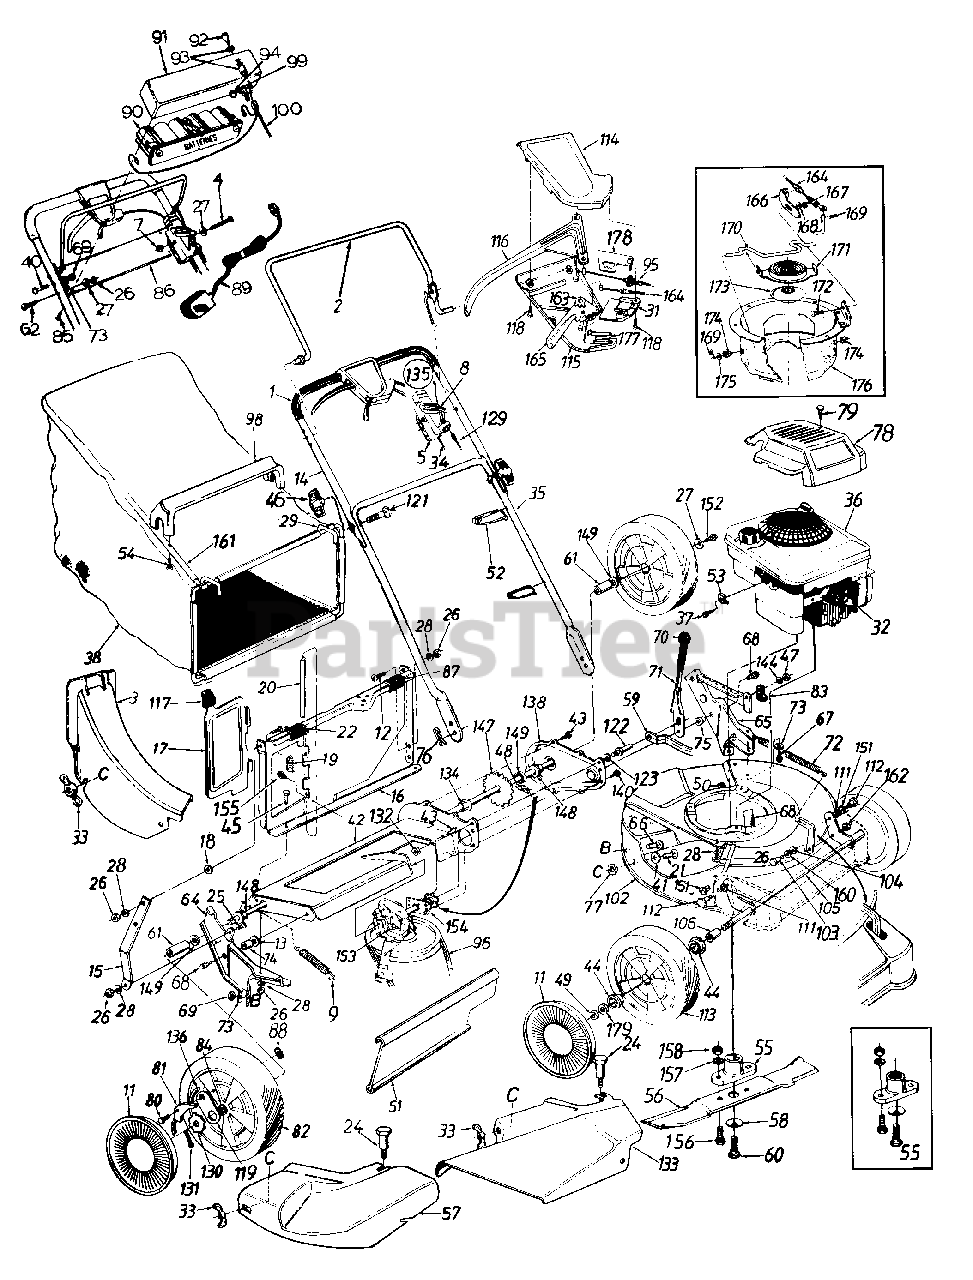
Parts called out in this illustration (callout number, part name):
1	Foam Grip
3	Rear Discharge Chute Ass'y.
4	Hex Bolt 1/4-20 x 2" Lg.
5	Throttle Body
7	Hex L-Nut 1/4-20 Thd.
8	Throttle Lever
9	Ext. Spring 3.8" Lg.
11	Hub Cap
12	Truss Mach. Scr. 1/4-20 x .62" Lg.
13	FL-Wash. .383" I.D. x 1" O.D.
19	Torsion Spring
20	Pivot Pin
21	Carriage Bolt 1/4-20 x .62"
22	Truss Mach. Scr. 1/4-20 x 3/4" Lg.
24	Shoulder Bolt .312 Dia. x . .18 Lg.-Special
25	Hex Bolt 1/4-20 x .62" Lg.
26	Hex Nut 1/4-20 Thd.
27	Bell-Wash. 1/4" I.D.
28	L-Wash. 1/4" I.D.
31	S.P. Control Cover
32	Spark Plug Insulator
33	Wing Nut w/Washer
34	Throttle Control Wire 61"
36	Engine
37	Hex Self-Tap Scr. #10-32 x .62" Lg.
38	Grass Bag
40	Curved Carr. Bolt 5/16-18 x 1.38" Lg.
41	FL-Wash. .344" I.D. x .62"
44	Ball Bearing 1/2" I.D.
45	Hex AB-Tap Scr. 1/4 x .62"
46	Hand Knob
47	Hex Patch L-Nut 3/8-24 Thd.
48	348 Chain .500" Pitch x 30 Links
49	Hex L-Nut 1/2-20 Thd.
51	Rear Flap 4.8" x 18" Lg.
52	Cable Tie
53	Cable Clamp
54	Hex AB Scr. #12 x 1.25" Lg.
55	blade Adapter Kit
56	21" Mulching Blade
57	Mulching Plug
58	Bell-Wash. .46" I.D.
59	Height Adj. Connecting Arm
60	Hex Bolt 7/16-20 x 1.5" Lg. (Grade 5)
61	Spacer .513" I.D. x .703" O.D. x .69" Lg.
62	Carr. Bolt 1/4-20 x 1.25" Lg.
64	R.H. Handle Wheel Brkt. Ass'y.
65	L.H. Handle Wheel Brkt. Ass'y.
66	Carriage Bolt 5/16-18 x .62"
67	Hex Wash. Hd. B-Tap Scr. 5/16-18
68	Hex Wash. Hd. TT-Tap Scr. 3/8-16
69	Hex Nut 5/16-18 Thd.
71	Height Adj. Lever
72	Extension Spring .75" O.D. x 8" Lg.
73	Bell-Wash. 5/16" I.D.
74	Spacer
75	Shld. Spacer .500" Dia.
76	Hairpin Clip
77	Bolt Retainer 1/4 x .50" O.D.
78	Engine Shroud
79	Screw #10 x 1.25" Lg.
80	Shld. Scr. .342" Dia. x .268"
81	Pawl
82	Rear Wheel Ass'y. Comp.
83	Clamp
84	Bearing 1/2" I.D.
85	Truss Mach. Tap Scr. 1" Lg.
88	Weld L-Nut 1/4-20 Thd.
89	Battery Charger
90	Battery Pack-12 Volt
91	Battery Tray
92	Ignition Key
93	Ignition Switch
94	Fuse Holder
95	S.P. Cable
96	"V"-Belt
98	Bag Handle
99	Plug
100	Wire Harness
102	21" Deck Ass'y.
103	Shld. Bolt .5" Dia. x 295"
104	Bell-Wash. .515" I.D. x 1.0" O.D.
105	Front Axle Ass'y.
106	Sleeve .526" I.D. x .690" O.D. x .880" Lg.
111	Intern. L-Wash. 3/8" I.D.
112	Shld. Bolt .575" Dia. x .42
113	Front Wheel Ass'y. Comp.
114	Self-Propelled Control Cover
115	Self-Propelled Control Cover
116	Control Lever
117	Door Grip
118	FL-"C"-Sunk Hd. Tap Scr. #10 x .75" Lg.
119	Pawl Plate
121	Curved Hd. Bolt 5/16-18 x 2" Lg.
122	Shld. Pin 3/8-24 x 1.43" Lg.
123	L-Wash. 3/8" I.D.
129	Control Cable 43" Lg.
130	Ratchet Wheel 1.62" O.D.
131	Cotter Pin 1/8" Dia. x 1.00" Lg.
132	Hex Jam Nut 3/8-24 Thd.
133	Side Chute Deflector Ass'y.
134	Hex Flange Bearing
135	Throttle Box Comp.
136	Spring-Nylon
144	FL-Wash. .385" I.D. x .87"
147	Rear Shaft Ass'y. 21.94" Lg.
148	Hex Flange Bearing .506" I.D. Plastic
149	FL-Wash. .531" I.D. x .930"
151	Flanged Nyliner Brg.
152	Hex Bolt 1/4-20 x .62" Lg. (Grade 5)
153	Transmission Comp.
154	Hex Bearing Cup
155	Hex B-Tap Scr. #10 x .38
156	Hex Scr. 3/8-24 x 1.0" Lg.
157	L-Wash. 3/8" I.D.
158	Hex Nut 3/8-24 Thd.
160	FL-Wash. .51 I.D. x .75" O.D.
162	Hex Jam Nut 3/8-16 Thd.
163	3 Tooth Rack Gear Insert
164	Spd. Control Cable-50" Lg.
165	6-Spd. Shift Lever
168	Hex Cent. L-Nut 1/4-20 Thd.
169	Cot-Pin 3/32" Dia. x .75" Lg.
170	Shift Rod
171	Movable Pulley Half Ass'y.
172	Carr. Bolt 1/4-20 x .50" Lg.
173	Spined Pulley Half
174	Flanged Bushing
175	FL-Wash. .328" I.D. x .68" O.D.
178	6-Speed Rack Cable Brkt.
17055B-0637	AXLE ASSY-CHAIN - POWDER BLACK (0637)
17055B-0638	AXLE ASSY-CHAIN - MTD/TROY-BILT RED (0638)
17055B-0665	AXLE ASSY-CHAIN - YARDMAN GREEN (0665)
